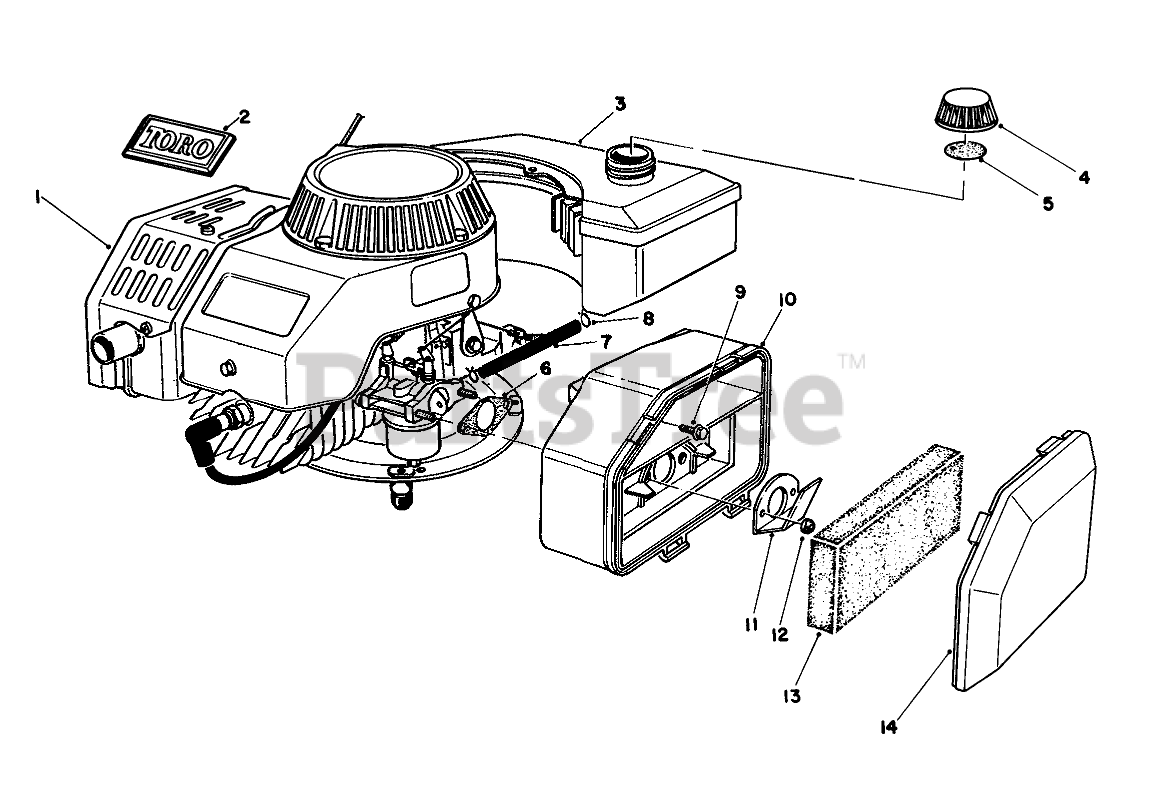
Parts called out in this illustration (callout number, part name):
1	Engine
2	TORO LOGO PLT
3	Gas Tank Assembly
4	Gas Cap Assembly (Incl. Ref. #5)
5	GAS CAP GASKET
6	GASKET-AIR CLEANER
7	FUEL LINE
8	CLAMP-HOSE
9	HEX FL HD M.6X1.0X25MM
10	AIR CLEANER
11	SPIT BACK DEFLECTOR
12	NUT-LOCK
13	FILTER
14	AIR CLEANER COVER
